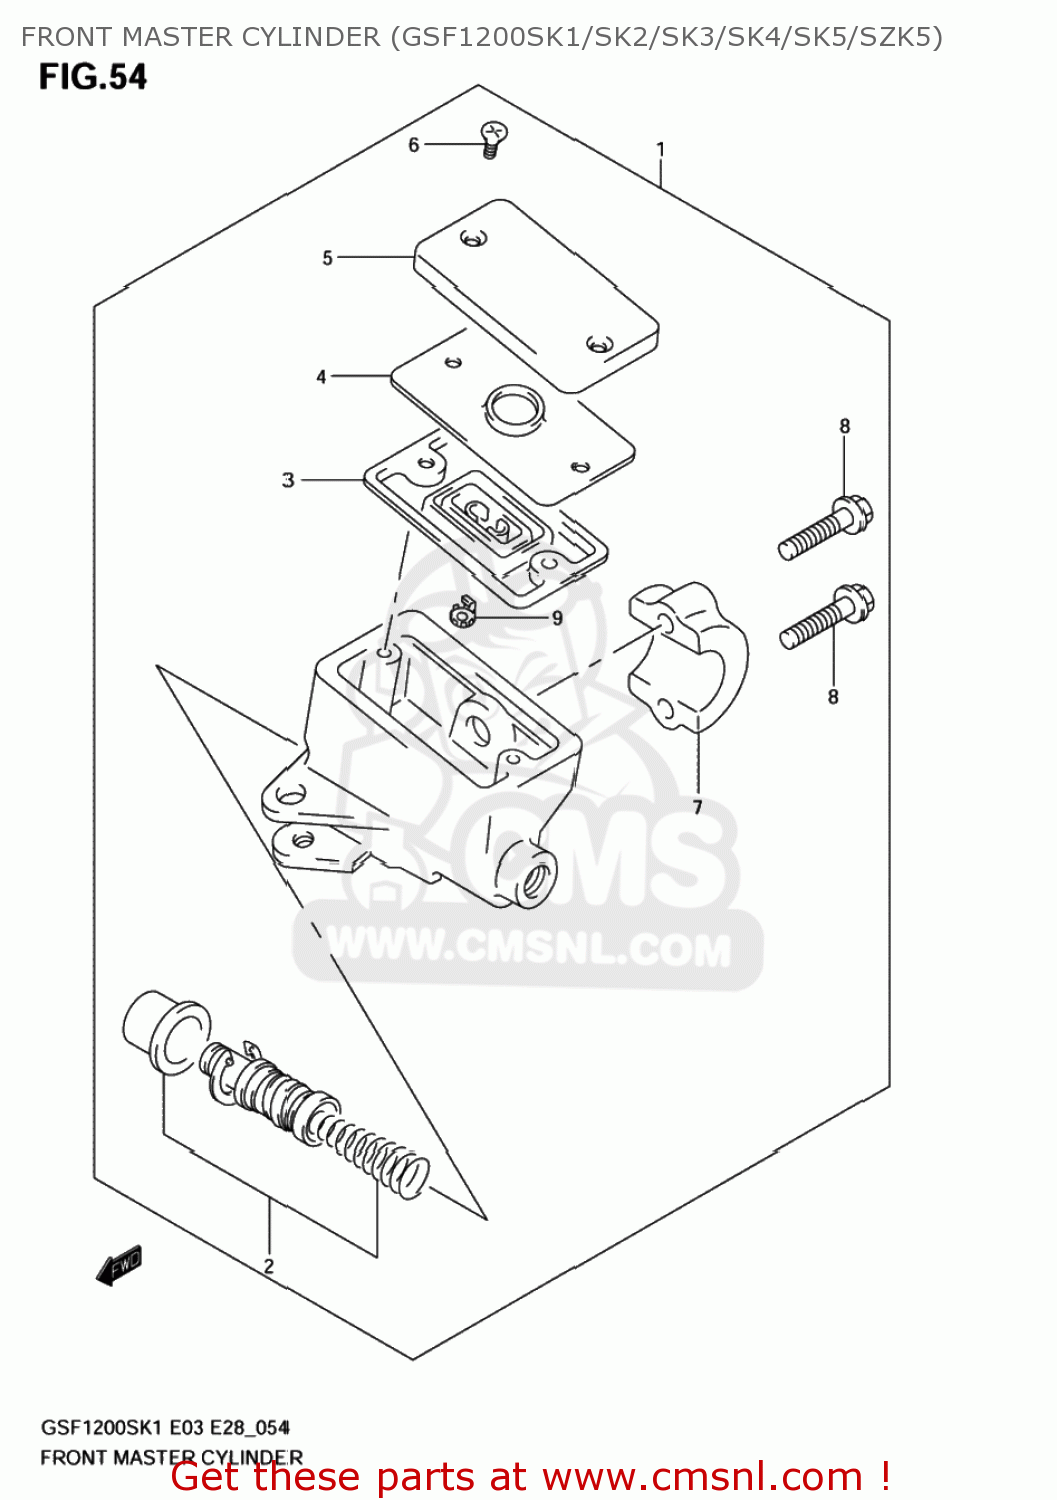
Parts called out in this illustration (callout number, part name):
1	CYLINDER ASSY,FR MASTER
2	PISTON & CUP SET
3	4
4	PLATE,DIAPHRAGM
5	CAP
6	SCREW
7	HOLDER
8	BOLT(6X25)
9	PROTECTOR
